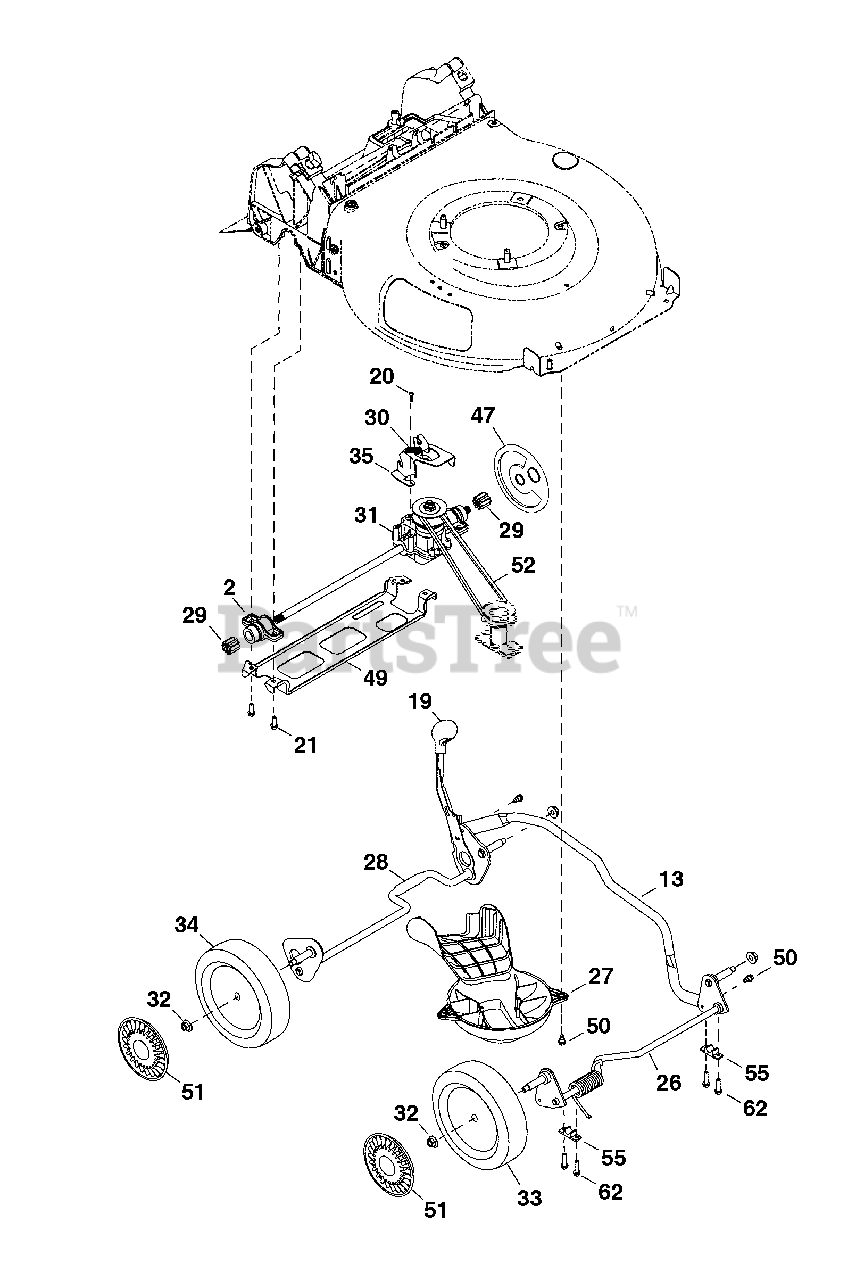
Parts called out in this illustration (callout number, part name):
2	ASSEMBLY, Bearing
13	SCREW, #10-16 X 1.00
19	KNOB, Adjustment Lever
20	SCREW, Hex Washer Head, .159 x .43
21	CAPSCREW, Hex Head Flange Taptite, 1/4-15 X 1-1/4
26	Front Axle Assembly
27	BAFFLE, Engine
28	AXLE ASSEMBLY, Rear
29	GEAR, 10T
30	SPRING, Extension, 2.405
31	TRANSMISSION
32	NUT, Hex Flange, Nylock, 3/8-16
33	WHEEL, Front
34	WHEEL, Rear
35	BRACKET, Transmission
47	DUST COVER, Wheel
49	Rear Support Bracket
50	SCREW, Shoulder, 1/4-20 x 1/2
51	HUBCAP, Front, 8" Grey
52	V-BELT, 3L, 31.25"
55	BUSHING, Bearing, Front Crossbar
62	SCREW, #10-16 X 1.00
